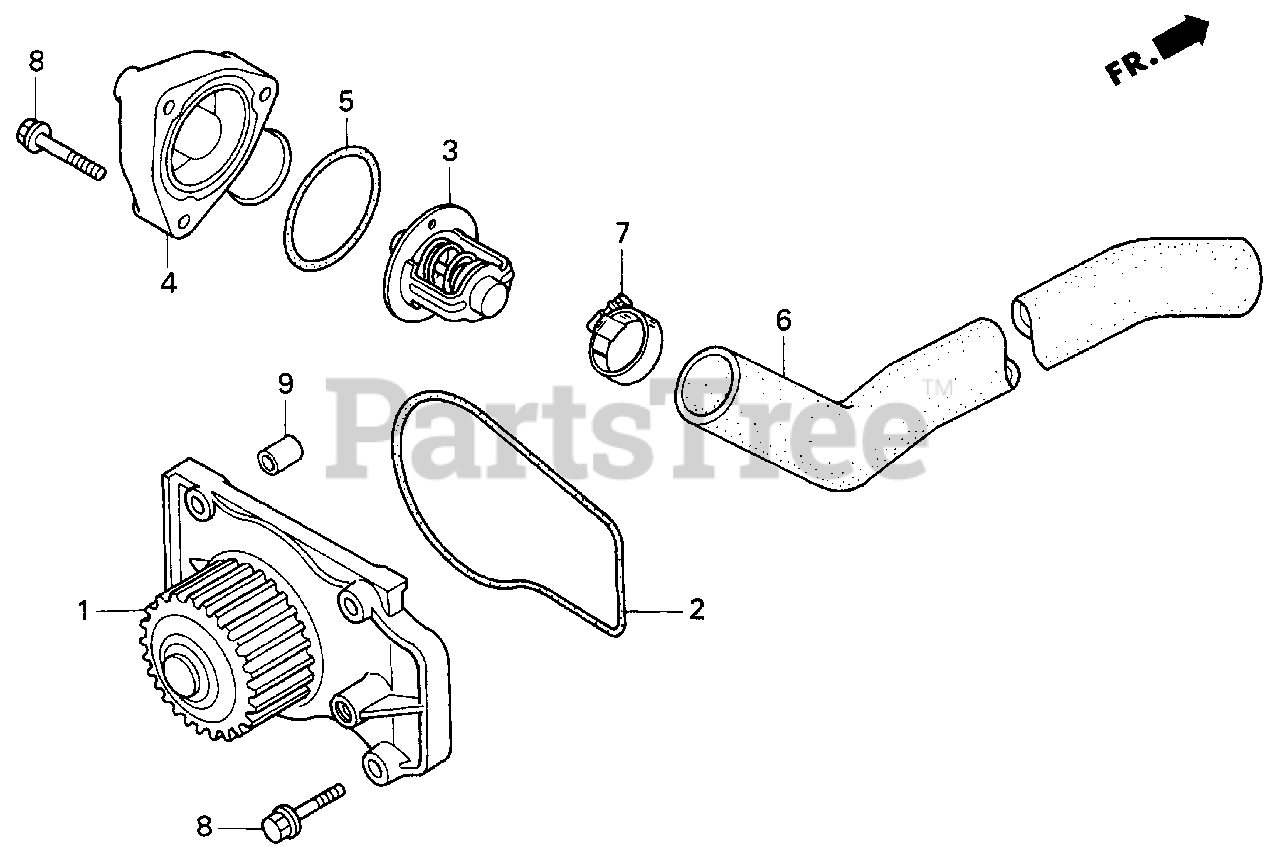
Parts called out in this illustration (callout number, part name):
1	WATER PUMP
2	O-RING, WATER PUMP
3	THERMOSTAT
4	COVER, THERMOSTAT
5	O-RING, THERMOSTAT COVER
6	HOSE B, WATER
7	BAND, WATER HOSE
8	BOLT, FLANGE (6X32)
9	PIN A, DOWEL (8X14)
